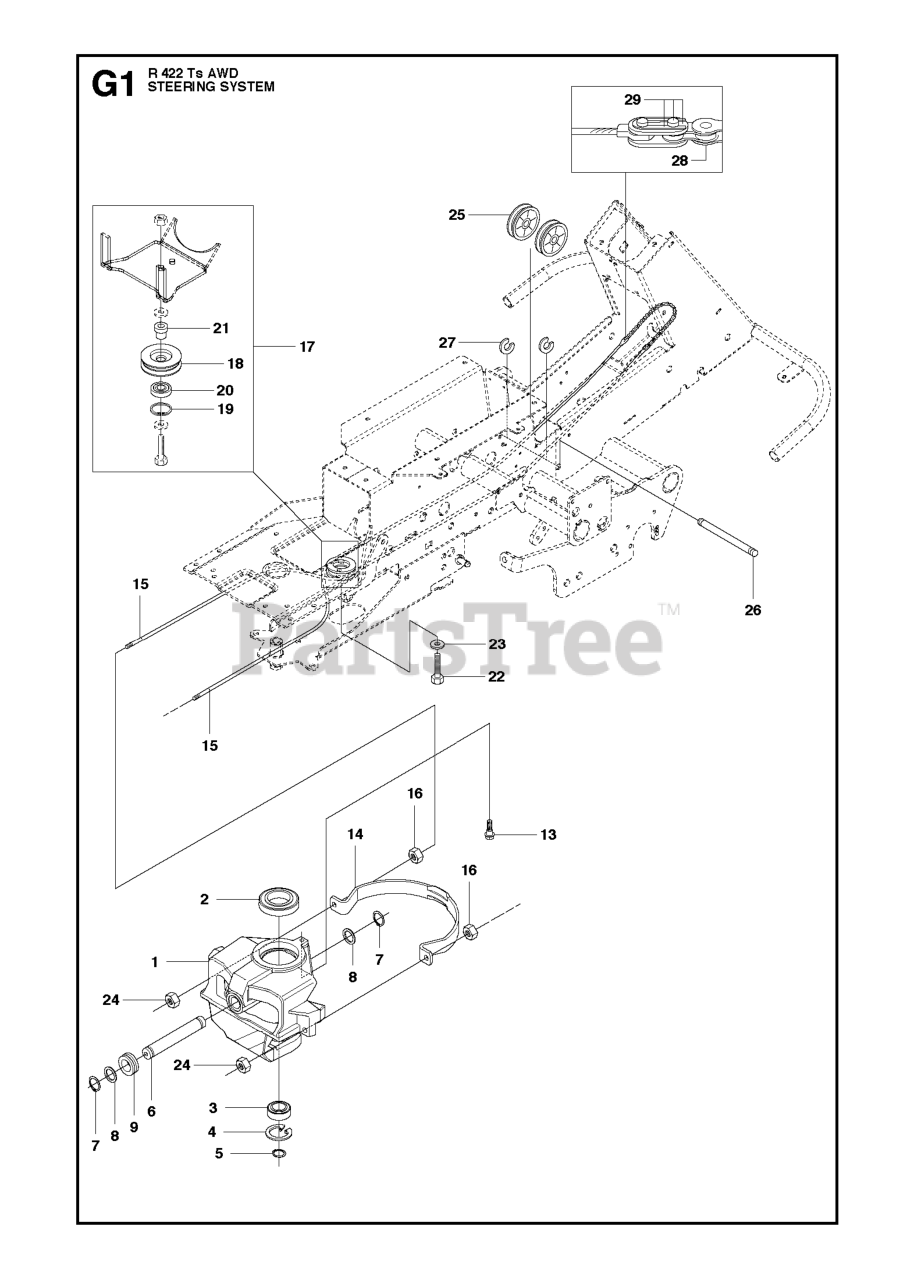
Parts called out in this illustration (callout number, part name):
2	BALL BEARING 6010 2RS1
3	Ball Bearing 6005-2rs
4	CIRCLIP SGH 47
5	RETAINING RING SGA 25
7	RETAINING RING SGA 25
14	WIRE GUIDE
15	WIRE ASSY
16	NUT
19	CIRCLIP SGH 47
20	BALL-BEARING 6204-2RS
22	REPL BY 725 25 00-71
24	NUT
26	SHAFT
27	RETAINING RING
28	STEERING CHAIN
